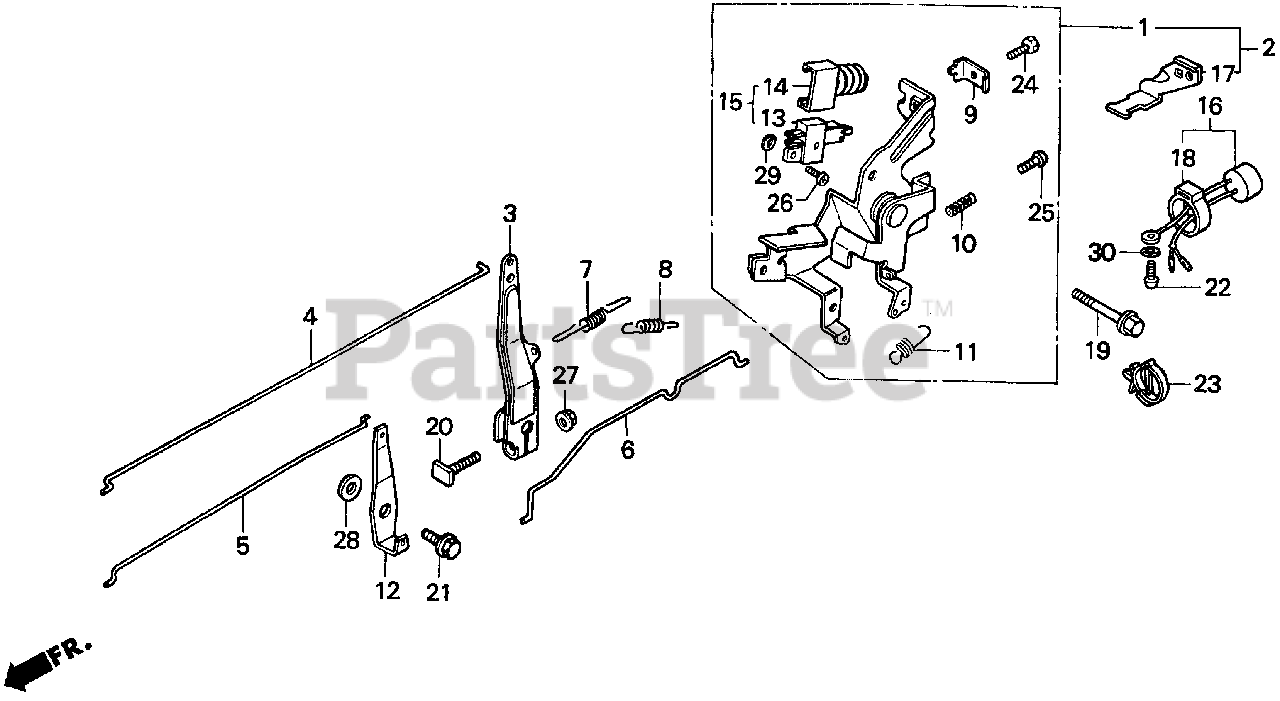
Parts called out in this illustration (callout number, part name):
2	CONTROL ASSY. (ALT)
3	ARM, GOVERNOR
4	ROD, GOVERNOR
5	ROD, CHOKE
6	ROD, JOINT
7	SPRING, GOVERNOR
8	SPRING, GOVERNOR PRIMARY
9	HOLDER, CABLE
10	SPRING, CONTROL ADJUSTING
11	SPRING, CABLE RETURN
12	LEVER, CHOKE JOINT
13	SWITCH ASSY., ENGINE
14	COVER, SWITCH
15	SWITCH ASSY., ENGINE STOP
16	BUZZER ASSY.
17	STAY, BUZZER
18	SUSPENSION, AUDIBLE PILOT
19	BOLT, FLANGE (6X12) (CT200)
20	BOLT, GOVERNOR ARM
21	BOLT, FLANGE (6MM)
22	SCREW, TAPPING (5X8)
23	CLIP, WIRE HARNESS
24	BOLT, SLOT (5X16)
25	SCREW, PAN (4X14)
26	SCREW, PAN (5X20)
27	NUT, FLANGE (6MM)
28	WASHER, PLAIN (6MM)
29	WASHER, SPRING (4MM)
30	WASHER, SPRING (5MM)
